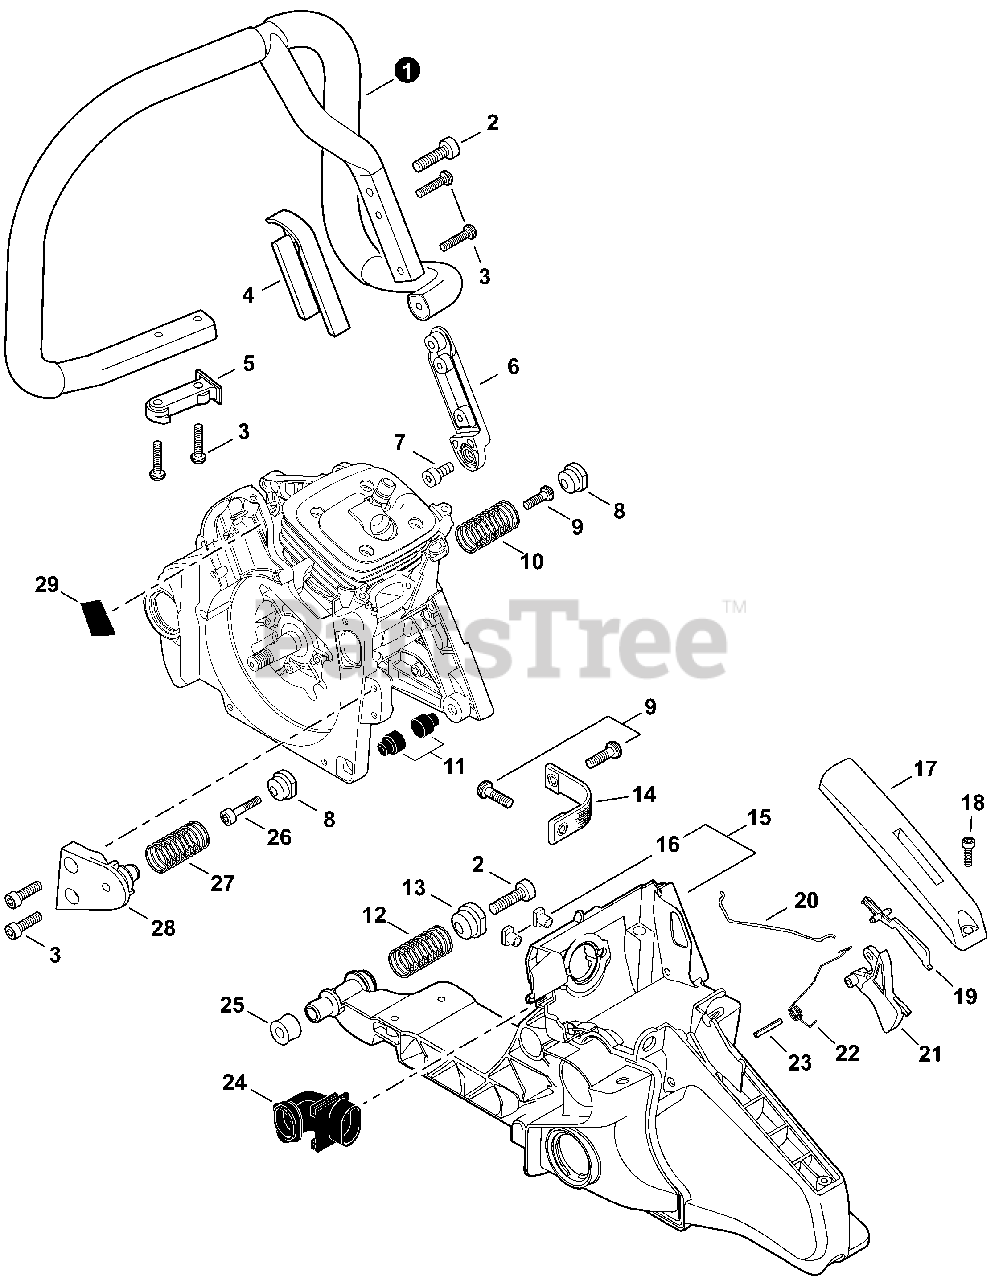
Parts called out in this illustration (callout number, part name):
1	HANDLE, FRONT
2	BOLT, TORX 6×20
3	BOLT, TORX 5×20
4	HOLDER, SPRING
5	MOUNT, HANDLE
6	BRACKET, HANDLE
7	BOLT, TORX 5×16
8	HOLDER, SPRING Ø14.4
9	BOLT, TORX 5×16
10	SPRING, COMPRESSION Ø17×38.4×2.6
11	CUSHION
12	SPRING, COMPRESSION Ø20×40×3.3
13	HOLDER, SPRING Ø17
14	STRAP, SAFETY
15	HANDLE, REAR
17	COVER, HANDLE
18	BOLT, TORX 4×12
19	LEVER, THROTTLE LOCKOUT
20	ROD, THROTTLE
21	TRIGGER, THROTTLE
22	SPRING, TORSION
23	PIN, SPRING 4×25 SUS
24	PIPE, AIR INTAKE
25	CUSHION 10
26	BOLT, TORX 5×25
27	SPRING, COMPRESSION Ø17×36.7×2.6
28	HOLDER, SPRING
29	CUSHION
